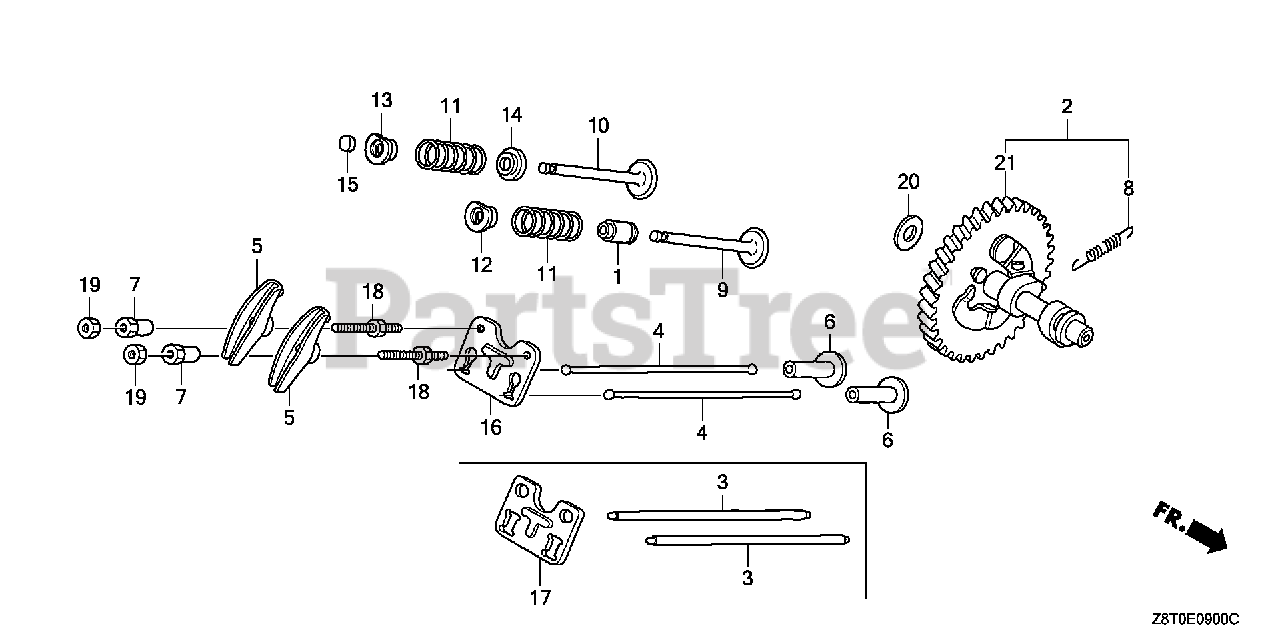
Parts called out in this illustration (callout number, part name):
1	SEAL, VALVE STEM
2	CAMSHAFT (STD) (PRESS FIT CAM)
5	ARM, VALVE ROCKER
6	LIFTER, VALVE
7	PIVOT, ROCKER ARM
8	SPRING, WEIGHT RETURN
9	VALVE, IN.
10	VALVE, EX.
11	SPRING, VALVE
12	RETAINER, IN. VALVE SPRING
13	RETAINER, IN. VALVE SPRING (EXHAUST SIDE)
14	SEAT, VALVE SPRING
16	GUIDE, PUSH ROD
18	BOLT, PIVOT (8MM)
19	NUT, PIVOT ADJUSTING
21	CAMSHAFT (STD) (PRESS FIT CAM)
